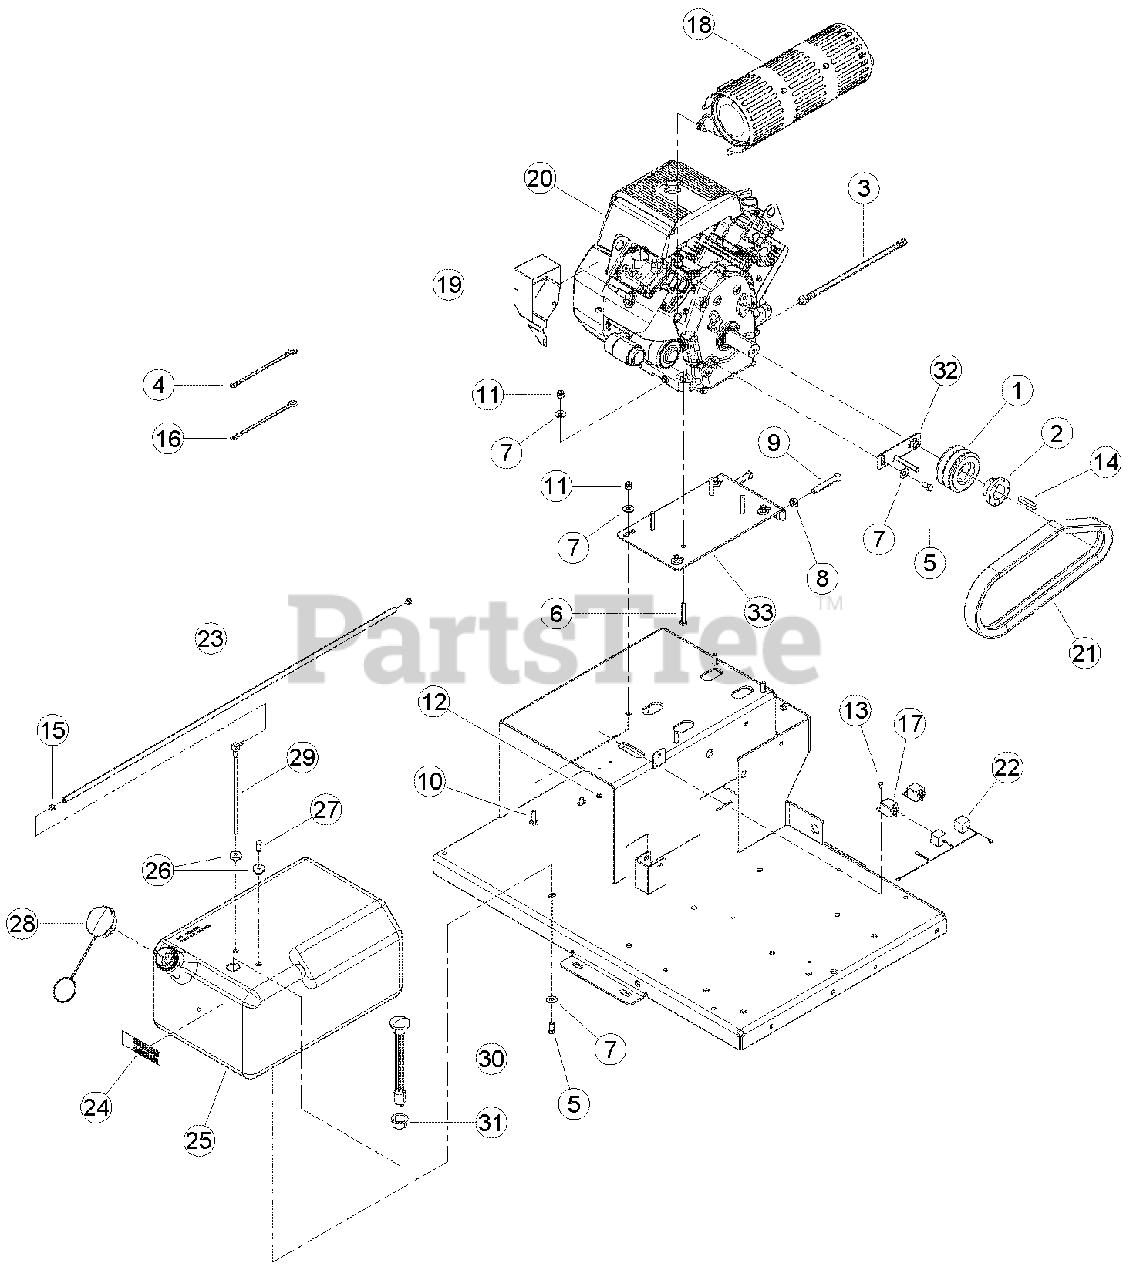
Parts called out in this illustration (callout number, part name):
1	SHEAVE, 2B3.6 SH, QD
2	BUSHING, SH 1-7/16
3	HOSE ASSY, CRANKCASE DRAIN
4	CABLE, 24" NEG (R / R)
5	BOLT 3/8*3/4 GR5 HEX CAPSCW ZP
6	BOLT 3/8*2 GR5 HEX CAPSCREW ZP
7	WASHER, 3/8" FLAT ZP (67PCS/LB)
8	NUT, 1/2 NC ZP JAM
9	SETSCREW, 1/2X3 SQ HD 1/2 DOG PT
10	BOLT, CARR 3/8*1-1/4"GR5 NC ZP
11	NUT, 3/8" NE NYLOCK ZP
12	NUT, 10/24 NYLOCK TYPE NM, ZP
13	SCW,MCH 10-24*1/2"PAN HD,PH ZP
14	KEY, .375 X .230
15	CLAMP, 15/32 SPRING
16	CABLE, 33" POS (R / R WITH BOOT)
17	RELAY, 12V SPDT W/ FLANGE
18	MUFFLER, SUBARU V-TWIN (FOR SERVICE SEE ENGINE OWNER'S MANUAL OR NEAREST AUTHORIZED SUBARU INDUSTRIAL ENGINE DEALER)
19	CONTROL, SUBARU V-TWIN IGNITION (FOR SERVICE SEE ENGINE OWNER'S MANUAL OR NEAREST AUTHORIZED SUBARU INDUSTRIAL ENGINE DEALER)
20	ENGINE, SUBARU 720CC EH72 (FOR SERVICE SEE ENGINE OWNER'S MANUAL OR NEAREST AUTHORIZED SUBARU INDUSTRIAL ENGINE DEALER)
21	BELT, 2RB40
22	HARNESS, CARB SAFETY RELEAY
23	HOSE, 43 INCH FUEL LINE
24	DECAL, UNLEADED GASOLINE
25	TANK, 9.25 GAL ROTOMOLDED FUEL
26	GROMMET, TANK FITTING
27	PLUG, TANK VENT
28	CAP, FUEL TANK VENTED
29	FITTING, TANK FUEL PICK-UP TUBE
31	GROMMET, KELCH 100 GAUGE
32	WELDMENT, BELT GUIDE
33	WELDMENT, ENGINE ADJUSTER
